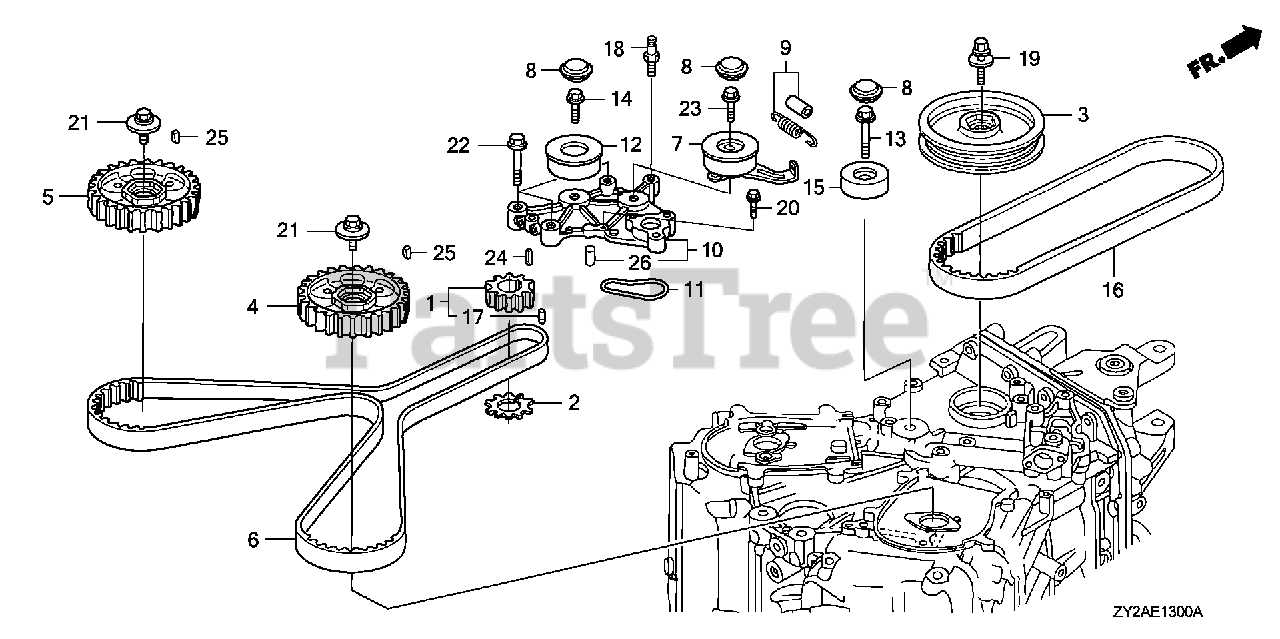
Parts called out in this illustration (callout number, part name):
1	PULLEY, TIMING BELT DRIVE
2	PLATE, TIMING BELT GUIDE
3	PULLEY, CRANKSHAFT
4	PULLEY, R. TIMING BELT DRIVEN
5	PULLEY, L. TIMING BELT DRIVEN
6	BELT, TIMING (197YU26 GB-323)
7	TENSIONER, TIMING BELT
8	CAP, TIMING BELT TENSIONER
9	SPRING, TIMING BELT ADJUSTING
10	BASE, TIMING BELT TENSIONER *NH8* (DARK GRAY)
11	O-RING, TIMING BELT TENSIONER BASE
12	IDLER, TIMING BELT (KOYO SEIKO)
13	BOLT, IDLER
14	BOLT, TIMING BELT IDLER A
15	IDLER B, TIMING BELT
16	BELT, ALTERNATOR (6PK745 M-180)
17	PIN, VERTICAL SHAFT
18	BOLT, TIMING BELT ADJUSTING SPRING
19	BOLT-WASHER (16X49)
20	BOLT, FLANGE (6X22)
21	BOLT-WASHER (12X35)
22	BOLT, FLANGE (10X40)
23	BOLT, FLANGE (10X43)
24	KEY (4.5X24)
25	KEY, SPECIAL
26	PIN, DOWEL (6X10)
